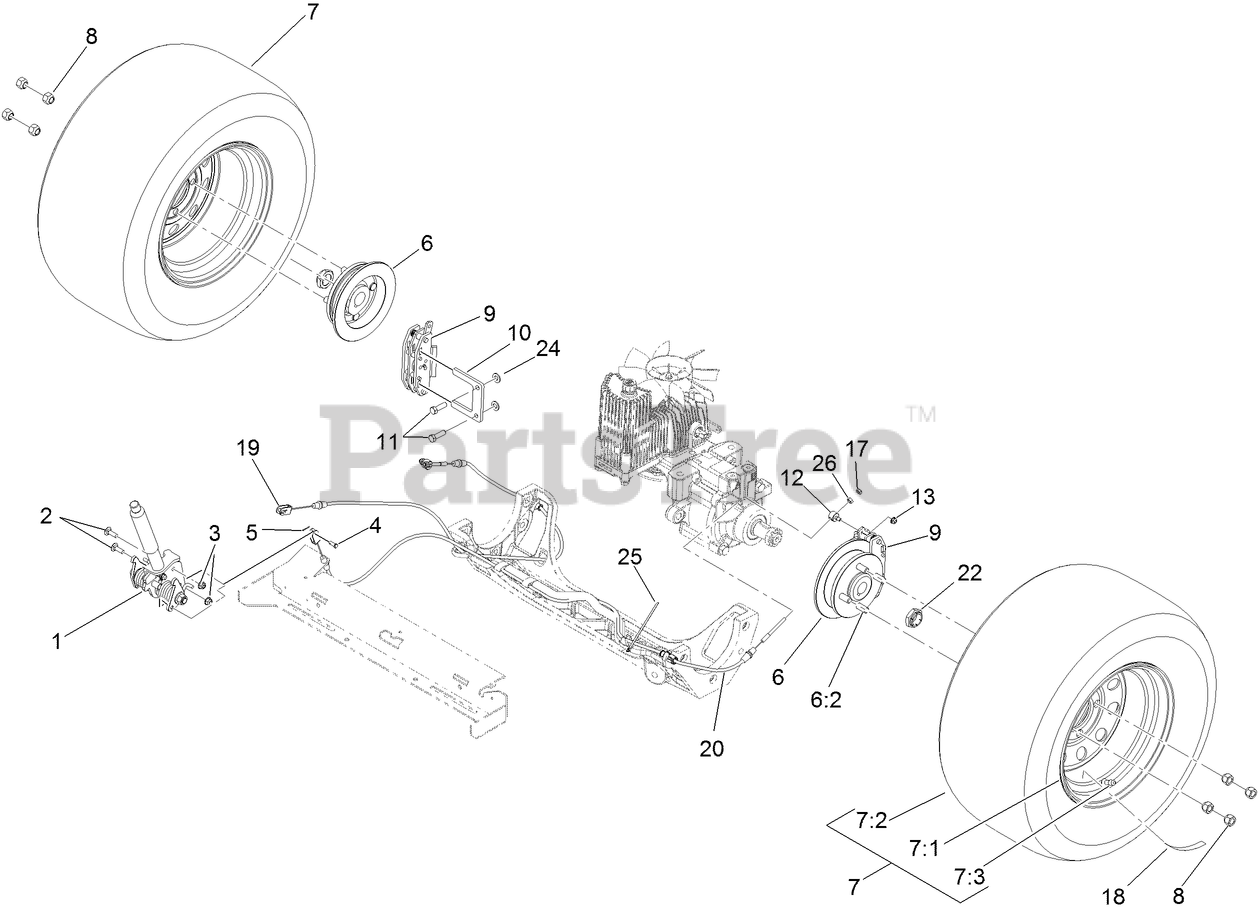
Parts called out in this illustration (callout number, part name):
1	BRAKE HANDLE ASM
2	BOLT-CARR
3	NUT-HF, NI
4	PIN-CLEVIS
5	PIN-COTTER
6	WHEEL HUB ASM
6:2	STUD-WHEEL
7	WHEEL AND TIRE ASM
7:3	STEM-VALVE
8	NUT-LUG
9	CALIPER-BRAKE
10	PLATE-MOUNT, BRAKE
11	SCREW-LOCK, PATCH
12	SWIVEL
13	NUT-HF
17	NUT-LOCK, NI
18	DECAL-WHEEL NUT TORQUE
22	LOCKNUT
24	WASHER-FLAT
25	TIE-CABLE
26	NUT-HEX
